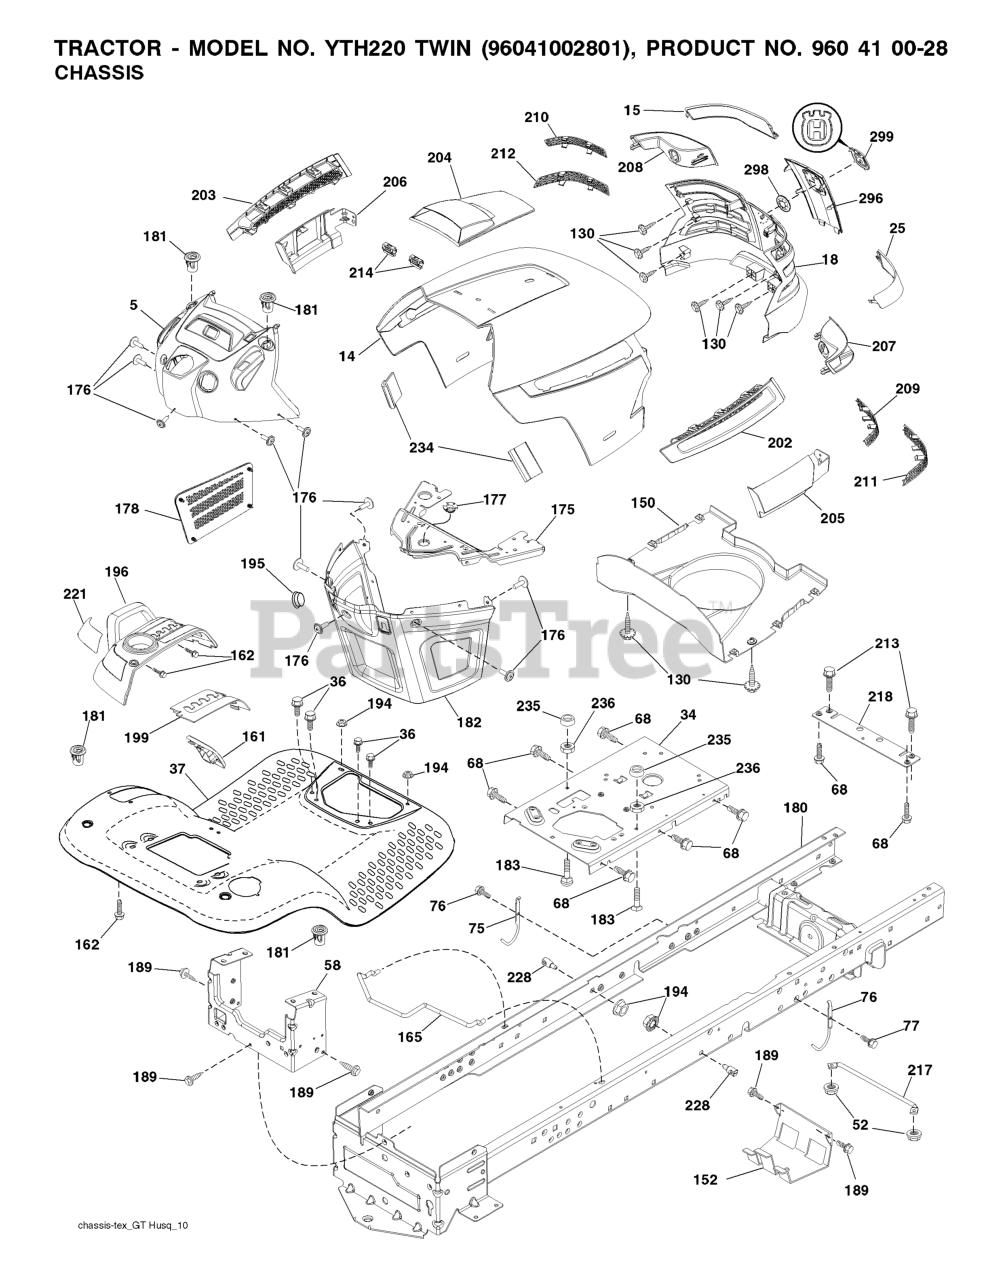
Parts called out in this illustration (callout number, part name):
3	RP LOGO
5	DASH.ASM.HUSQ.GT.E.RECT.W/CK
14	HOOD
15	LENS.LH.TEX.GT.HUSQ.CL
18	GRILL.ASM.HUSQ.TG/CRD.W/TRIM
25	LENS.RH.TEX.GT.HUSQ.CL
34	PLATE.ENGINE.WELDED.CHASSIS
36	SCREW 5/16"
37	FENDER.PNT.TX.GT.CH/FW.ORANGE
58	DRAWBAR.UPPER.2PC,LRG.FENDER
68	Screw 5/16-18 x 1/2 Hex, Self Tapping 5/16-18 x 1/2
75	ROD UPSTOP
76	ROD UPSTOP
77	SCREW 3/8-16X1
99	ROD ASM BYPASS
130	SCREW
137	BUMPER DASH
150	AIR.DUCT.HOOD.TEX.GT.HUSQ
152	SHIELD.BROWNING.W/TEX
161	CONSOLE.FUEL.WINDOW.HU
162	SCREW.HI-LO.CONSOLE
165	SUPPORT.TANK.REAR.W/TEX
175	PLATE.CROSSMEMBER.HUSQ
176	SCREW.#10-24X5/8.RN.QU
177	BUSHING, STEERING
178	CARGO.ASM.NET.TXGT.W/C
180	CHASS.WLDMNT.TL.12GA/2P.48/54
181	BUSHING.MNT.FEND.CRGO.
182	DASH.LOWER.COMMON.12V.ADAPTOR
183	BOLT.5/16-18X1-1/4 FULL.THREAD
189	SCREW
194	NUT LOCK HEX FLANGE 5/16-18
196	RP CONSOLE.ASM.DECKLFT.W/
199	PLATE.DECK.LIFT.HUSQVARNA.GT
202	VENT.SIDE.HOOD.HUSQ.RH.GREY
203	VENT.SIDE.HOOD.HUSQ.LH.GRAY
204	HOOD VENT
205	SKIRT.HOOD.SIDE.HUSQ.RH.GREY
206	SKIRT.HOOD.SIDE.HUSQ.LH.GREY
207	BEZEL.RH.TEX.GT.HUSQ
208	BEZEL.LH.TEX.GT.HUSQ
209	INSERT.HEX.GRILL.HUSQ.GREY
210	INSERT.HEX.GRILL.HUSQ.
211	INSERT.HEX.GRILL.HUSQ.
212	INSERT.HEX.GRILL.HUSQ.
213	BOLT
214	CLIP.RETAINER.TINNER.
217	ROD.PIVOT.HOOD
218	X-PIECE.HOOD.STOP.NON/
221	REFLECTOR.LH.TEX GT HU
228	STUD.FASTNER.W/ANTI-ROTATE
234	BUMPER.HOOD.TEX.HUSQVARNA
235	SPACER FENDER
236	NUT.CENTERLOCK.5/16-
238	TRIM.HUSQ.TG/CRD.SERVICE
239	NUT PUSH M
